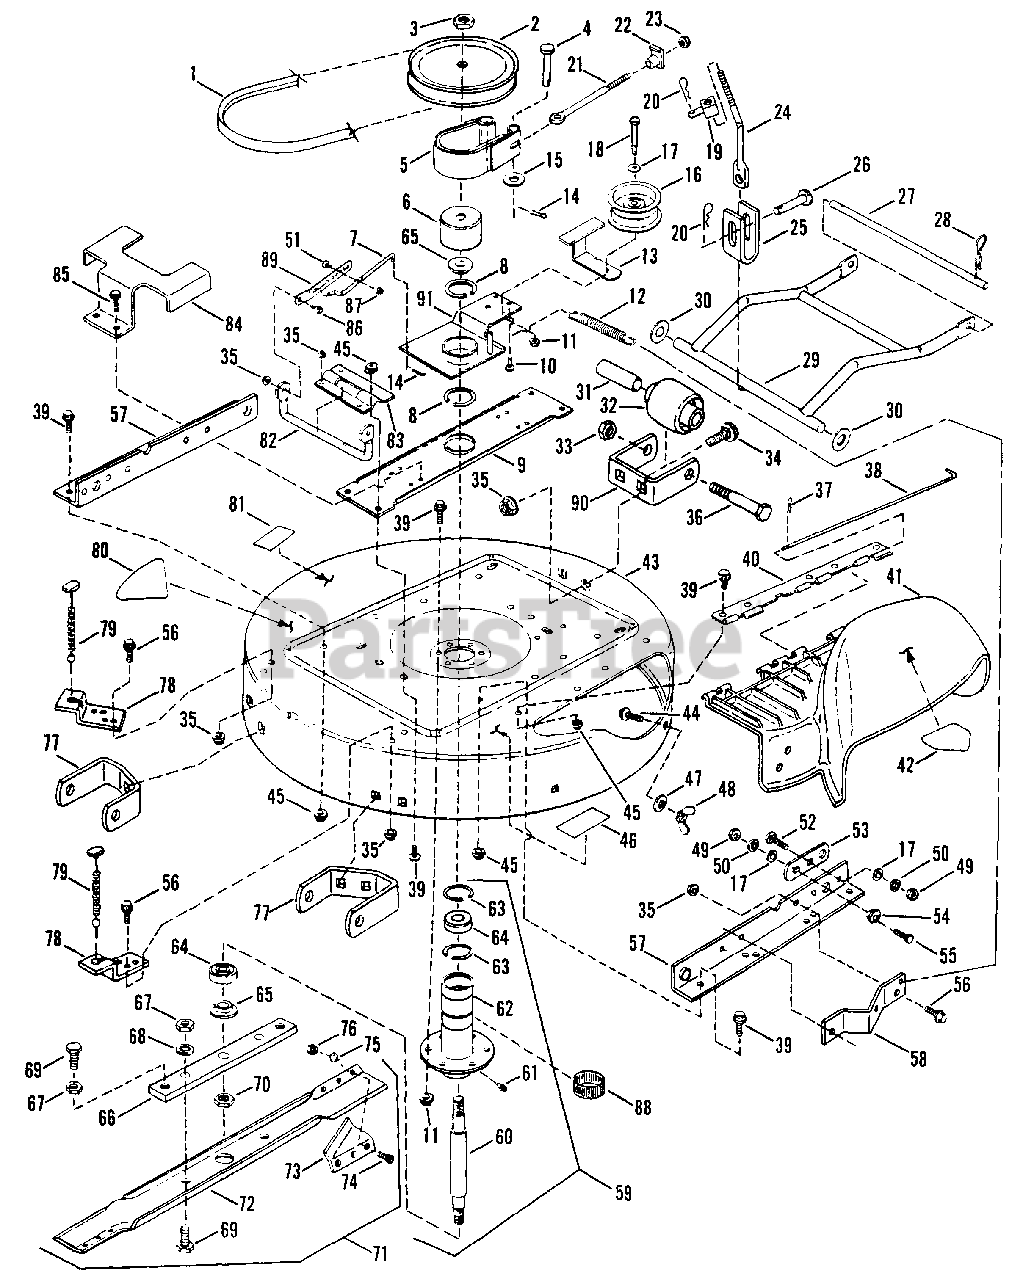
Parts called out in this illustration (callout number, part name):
1	BELT, 33" Drive, 56.95" EL
2	PULLEY, Spindle, 7" O.D.
3	NUT, 3/4-16 Hex Jam
4	PIN, 1/4 x 1 1/4" Clevis
5	BAND, Brake
6	DRUM, Brake
7	ROD, Link, Clutch/Brake
8	RING, 2" External Retaining
9	BRACE, Spindle
10	SCREW, 5/16-18 x 3/4" Self-Tapping
11	NUT, 3/8-16 Hex Cntr. Lock
12	SPRING, Clutch & Brake
13	GUIDE, Belt
14	COTTER-PIN, 3/32 x 3/4"
15	WASHER, Flat
16	PULLEY, Idler 4.0" O.D. (Flat 3.25" Running Surface)
17	WASHER, 3/8 SAE (3)
18	BOLT, 3/8-16 x 1 3/4" Hex Hd.
19	SWIVEL, Brake
20	PIN, 1/4 x 1 1/8" Hair
21	BOLT, 1/4-20 Eye
22	NUT, 1/4-20 Tee
23	NUT, 1/4-20 Hex
24	ROD, Front Lift
25	BRACKET, Front Lift Hanger
26	PIN, 3/8 x 1 1/2" Clevis
27	PIN, Front Deck Hanger
28	PIN, .148 x 2.62" Hair
29	LIFT, Front Arm
30	WASHER, Flat
31	SPACER
32	WHEEL, Gage
33	NUT, 3/8-24 Hex Lock
34	BOLT, 5/16-18 x 1/2" Short Neck Carriage
35	NUT, 5/16-18 Hex Flange Lock
36	SCREW, 3/8-24 x 3 3/4" Hex Head Cap
37	PIN, Hair
38	PIN, Hinge
39	BOLT, 3/8-16 x 3/4" Hex Flange Lock
40	HINGE, Deflector
41	ASSEMBLY, Deflector
42	DECAL, Danger (Cut Finger)
43	DECK, Cutting, 33"
44	BOLT, 5/16-18 x 3/4" Short Neck Carriage
45	NUT, 3/8-16 Hex Flng. Lk.
46	DECAL - CAUTION (Deflector)
47	WASHER, 5/16 Flat
48	WING-NUT. 5/16-18
49	NUT, 3/8-16 Hex
50	WASHER, 3/8 Split Lock
51	BOLT, 1/4-20 x 1/2" Hex Flange Lock
52	BOLT, 3/8-16 x 3/4" Carriage
53	LINK, Adjustment
54	ECCENTRIC, Leveling
55	SCREW, 3/8-16 x 1" Hex Head Cap
56	BOLT, 5/16-18 x 1/2" Hex Flange Lock
57	RAIL, Side
58	ANCHOR, Brake
59	ASSEMBLY, Spindle
60	SPINDLE
61	FITTING, Lube (Press fit for .187 hole-no ball)
62	HOUSING, Spindle
63	RING, Retaining
64	BEARING, Spindle
65	WASHER, Spindle
66	HOLDER, Blade
67	NUT, 1/2-20 Hex Jam
68	WASHER, 1/2 Int. Tooth Lk.
69	SCREW, 1/2-20 Hex Head Cap
70	NUT, 5/8-18 Hex Lock
71	ASSEMBLY, Blade & Air Lift
72	BLADE, 33" Mower Deck
73	AIR-LIFT
74	SCREW, 5/16-24 x 11/16" Machine
75	WASHER, 5/16 Internal Tooth Lock
76	NUT, 5/16-24 Hex
77	BRACKET, Gage Wheel Rear
78	BRACKET, Rear Lift
79	CABLE, Deck Lift, Rear
80	DECAL, 33" Hi-Vac
81	DECAL - CAUTION
82	ARM, Pivot
83	BRACKET, Pivot Arm
84	GUIDE, Belt
85	SCREW, 5/16-18 x 5/8" Self-Tapping
86	SCREW, 5/16-18 x 3/4" Shoulder
87	NUT, 1/4-20 Hex Flange Lock
88	RING, Tolerance
89	BRACKET, Link, Clutch/Brake
90	BRACKET, Gage Wheel (Front)
91	ARM, Idler
